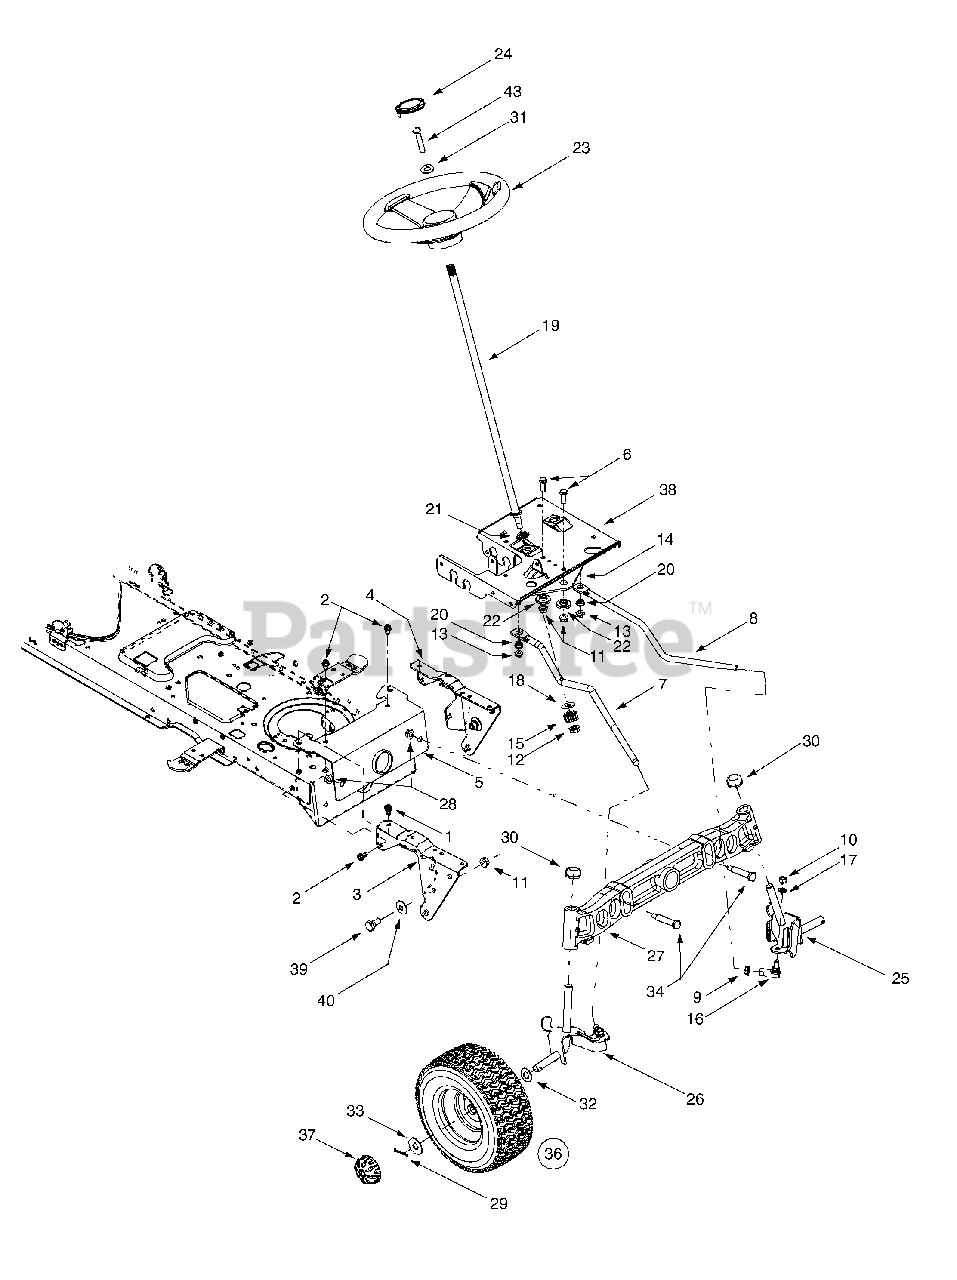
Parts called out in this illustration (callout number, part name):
1	Self-tapping Screw, 5/16-18 x .75
2	Self-tapping Screw, 16-18 x .625
6	Hex Cap Screw, 3/8-16 x 1
7	RH Drag Link
8	LH Drag Link
9	Jam Nut, 7/16-20
10	Hex Nut, 3/8-24
11	Flange Lock Nut, 3/8-16
12	Flange Lock Nut, 7/16-20
13	Flange Lock Nut, 5/16-18
14	Steering Gear, 11/90 Ratio
15	Steering Pinion Gear
16	Ball Joint, 7/16-20
17	Lock Washer, 3/8
18	Flat Washer, .51 x 1.12 x .06
19	Steering Shaft, .625 OD x 24.4
20	Plastic Bushing, .38 ID
21	Hex Flange Bearing, 5/8
22	Shoulder Spacer, .38 ID
23	Steering Wheel, Soft Grip, Three Spoke
24	Steering Wheel Cap, Round
25	LH Axle Assembly, .75 Diameter
26	RH Axle Assembly, .75 Diameter
27	Cast Iron Pivot Bar w/ Fittings, .75
28	Flange Lock Nut, 3/8-16
29	Cotter Pin
30	Push Cap, .750
31	Bell Washer, .34 x .872
32	Flat Washer, .78 x 1.59 x .06
33	Flat Washer, .635 x 1.589 x .06
34	Shoulder Screw, .5 x 2.2, 3/8-16
36	Air Valve
36	Tire Only, Square Shoulder
36	Plastic Flange
36	Plastic Flange w/Fitting
37	Hub Cap
39	Shoulder Screw, 3/8-16
40	Bell Washer, .39 x 1.13 x .062
43	Hex Screw, 5/16-18, 1.00, Gr5
